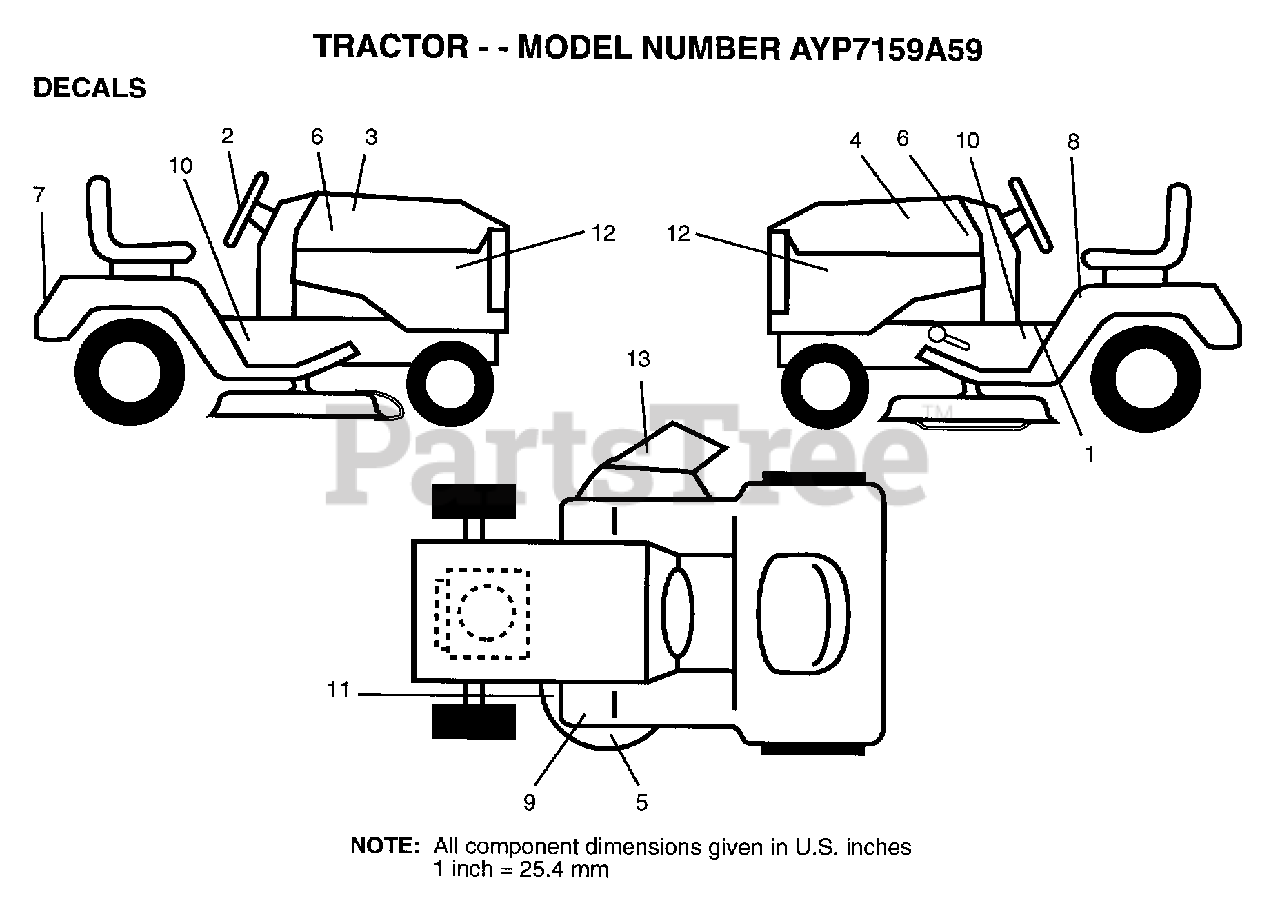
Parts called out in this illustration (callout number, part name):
2	DECAL STEER WHL
3	DECAL HOOD RH
4	DECAL HOOD LH
5	DECAL DECK WIZ +
6	NAMEPLATE.HD.WIZA
8	DECAL
10	DECAL CHASSIS WIZ
11	DECAL
12	DECAL.PNL.SD.VANG
13	DECAL DECK MULCH
